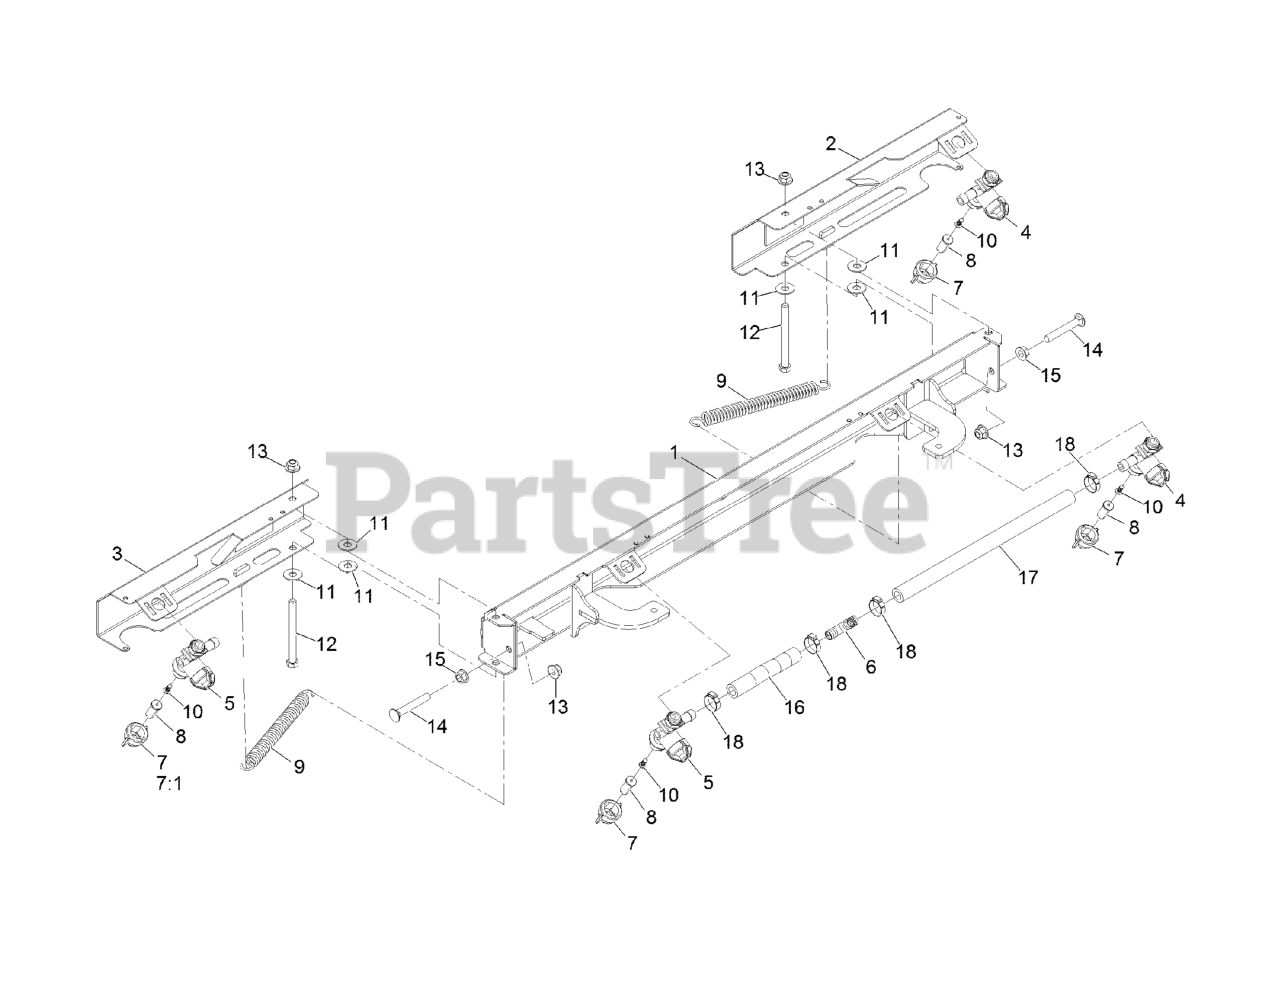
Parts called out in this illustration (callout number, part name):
1	Boom-Center
2	Boom-Wing, Rt
3	Boom-Wing, Lt
4	BODY-NOZZLE, RIGHT
5	BODY-NOZZLE, LEFT
6	FITTING-TEE, BARB
7	CAP-NOZZLE
7:1	SEAT-GASKET
8	TIP-SPRAY
9	SPRING-EXTENSION
10	STRAINER-NOZZLE, 50M 5PSI
11	WASHER-FLAT
12	SCREW-HH
13	Nut-Hex Flange
14	SCREW-CARR
15	Nut-Hex Flange
16	Hose-Spray
17	Hose-Spray
18	CLAMP-OETIKER, 167
